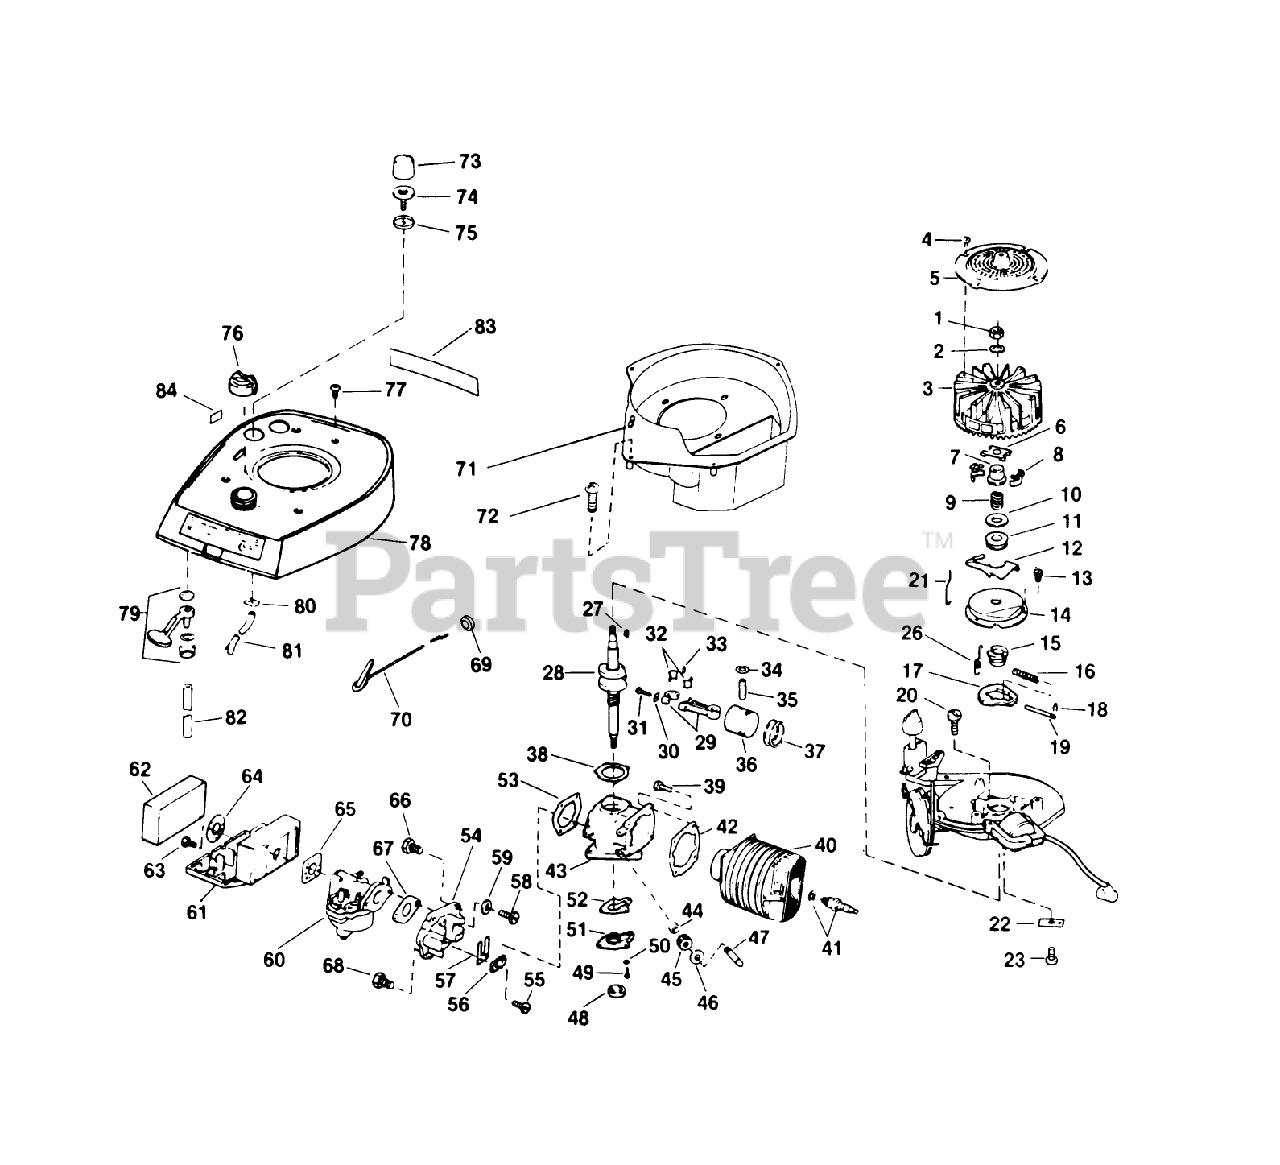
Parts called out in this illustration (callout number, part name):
4	SCREW F
5	FLYWHEEL SCREEN
7	COLLAR S
9	SPRING S
11	THRUST COLLAR S
12	LEVER-GOVERNOR S
13	SCREW S
14	DUST COVER S
15	SPARK ADV. S
16	SPARK ADV. SPRING S
17	FLYWEIGHT S
18	SPARK ADJ. SPRING
19	PIN,SPARK ADV. S
20	SCREW S
23	SCREW S
32	LINER ASM
34	RING-RETAINING
38	GASKET S
41	Spark Plug Gasket
42	GASKET S
45	GEAR, DR SHAFT S
46	THRUST WASHER
51	GEAR COVER S
52	GASKET-CVR S
53	GASKET S
54	REED PLATE AY. S
56	PLATE-BACKUP, REED
62	AIR FILTER S
63	SCREW S
64	WASHER S
65	GASKET S
66	SCREW S
67	GASKET S
68	SCREW S
69	GROMMET
70	KNOB & ROD AY. S
75	CUP-BULB
77	SCREW S
80	LOCKNUT S
